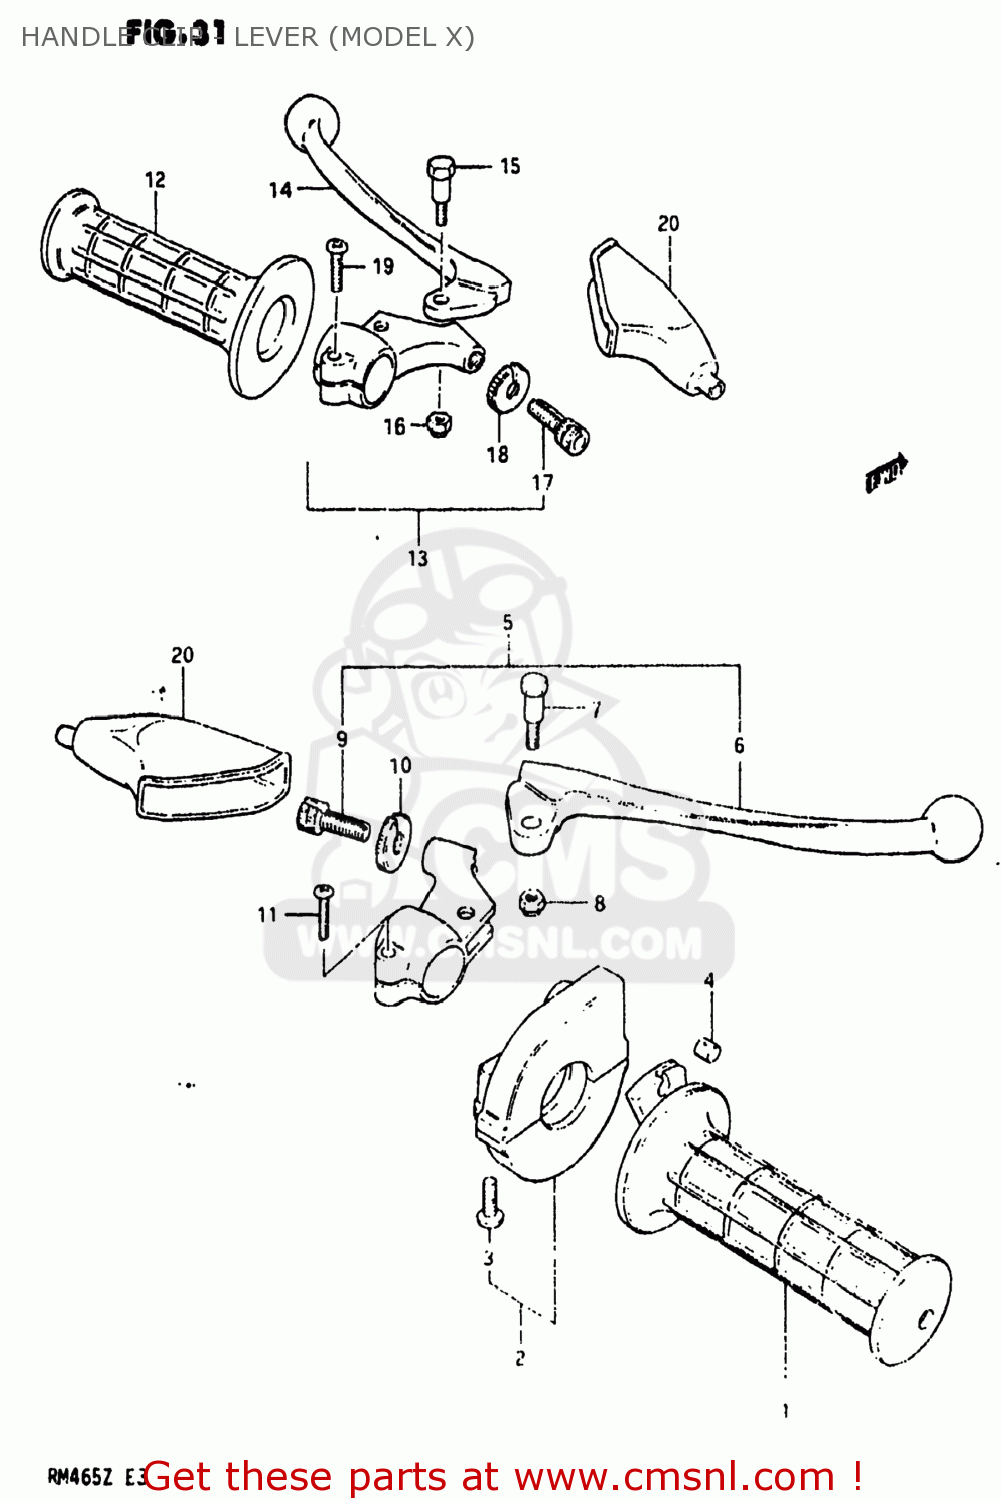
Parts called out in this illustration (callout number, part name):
1	GRIP,THROTTLE
2	CASE ASSEMBLY,THROTTLE
3	SCREW
4	PIECE,THROTTLE END
5	LEVER ASSEMBLY,BRAKE
6	LEVER,BRAKE
7	BOLT,LEVER
8	NUT 6MM
9	ADJUSTER,CABLE
10	NUT,CABLE ADJUSTER
11	SCREW
12	GRIP,LEFT
13	LEVER ASSEMBLY,CLUTCH
14	LEVER,CLUTCH
15	BOLT,LEVER
16	NUT 6MM
17	ADJUSTER,CABLE
18	NUT,CABLE ADJUSTER
19	SCREW
20	COVER,CLUTCH LEVER
